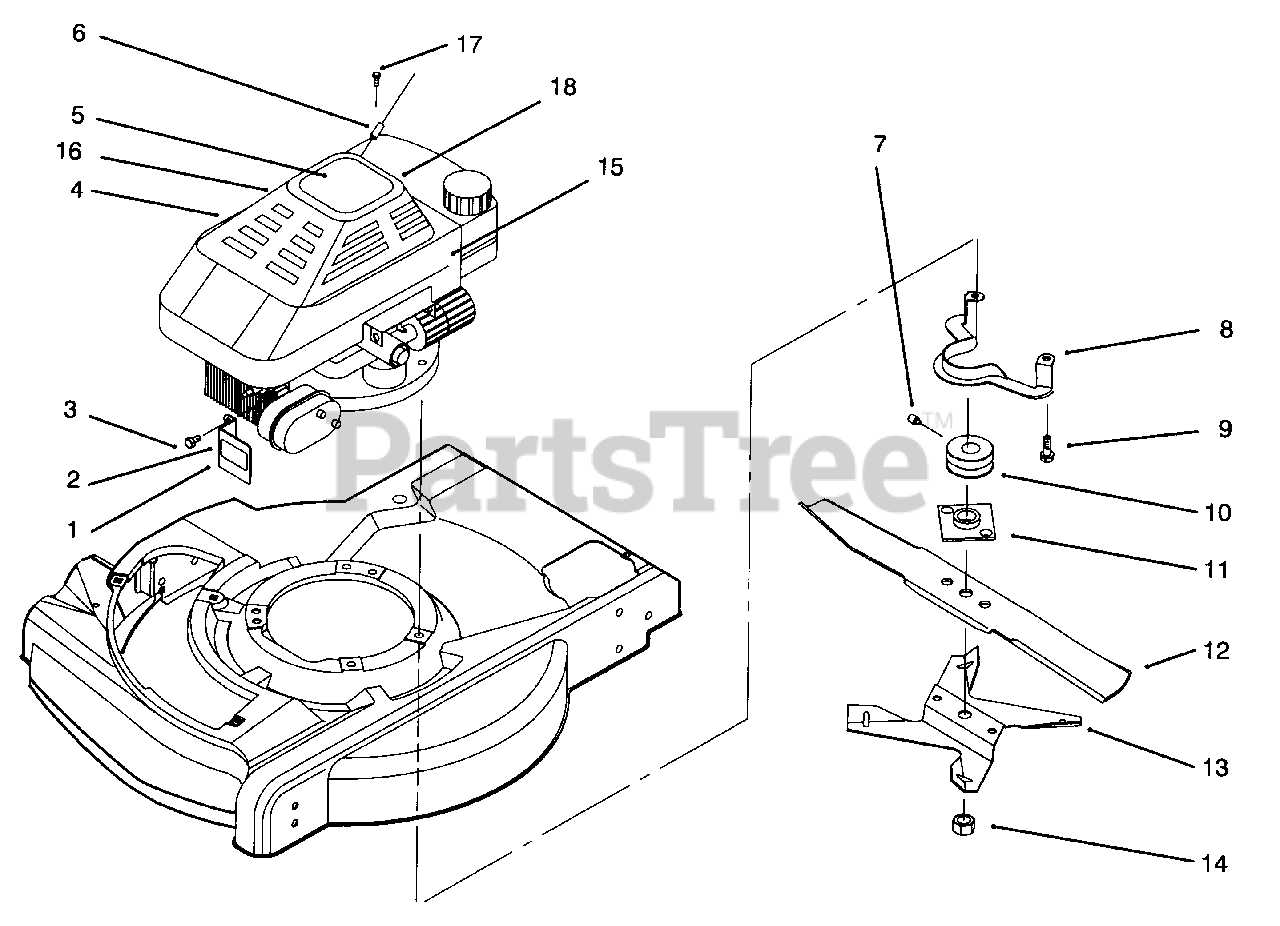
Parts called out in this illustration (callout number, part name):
1	Guard-Muffler (Incl. Reef.#2)
2	Decal-Warning
4	Engine-4 Cycle
5	Decal-Shroud
6	Stop-Rope
7	Screw-Set
8	Guide-Belt
9	Screw-Engine Mount
10	Pulley-Engine
11	Plate & Collar Ass'y
12	Blade-21 "
13	Fan-Mulching
14	Nut-Blade
15	Decal-Oil
16	Cover-Recoil
18	Shroud
